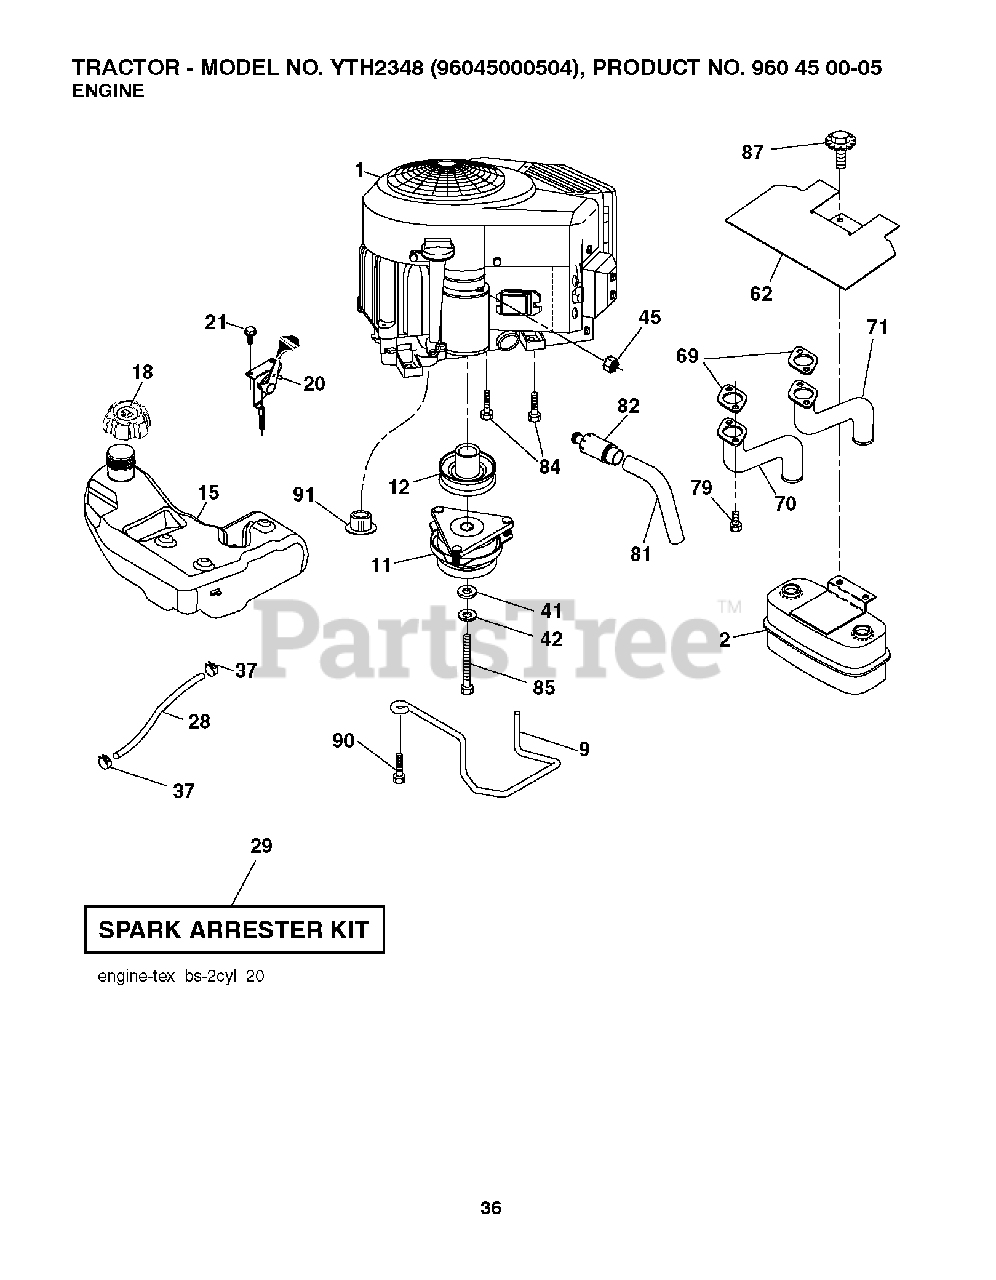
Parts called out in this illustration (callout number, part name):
1	Husqvarna TBD
2	MUFFLER.TWIN.CYL.LOW.TONE
9	KEEPER.BELT.ENGINE.4.2
11	CLUTCH.ELECTRIC.LT.48"*
12	PULLEY.ENGINE.TUFFTORQ
15	TANK.FUEL.SIDE-FILL.3.NON-EPA
18	CAP.FUEL.TANK.3"GREY
20	CONTROL.TH/CK.COBRA.B&S.TWN.
21	SCREW.#10 X 0.750.BOS
28	LINE.FUEL.64"REAR.EMIS
29	KIT.SPARK ARRESTOR 794945 B&S
37	HOSE CLAMP
42	LOCKWASHER
45	NUT
62	RP SHIELD HEAT MUFFLER
69	GASKET.MUFFLER
70	RP.EXHAUST.TUBE.LH.BS/TWIN
71	EXHAUST.TUBE.RH.BS/TWIN
79	SCREW.SOCKET.HEAD.5/16-18
81	TUBE, DRAIN OIL ASM.
82	PLUG DRAIN OIL EASY
84	SCREW.3/8-16
85	BOLT HEX 7/16-20X4-1/4"
87	BOLT, 5/16-18 X 1 3/4
90	SCREW 3/8-16X1
91	BUSHING.1.375OD
